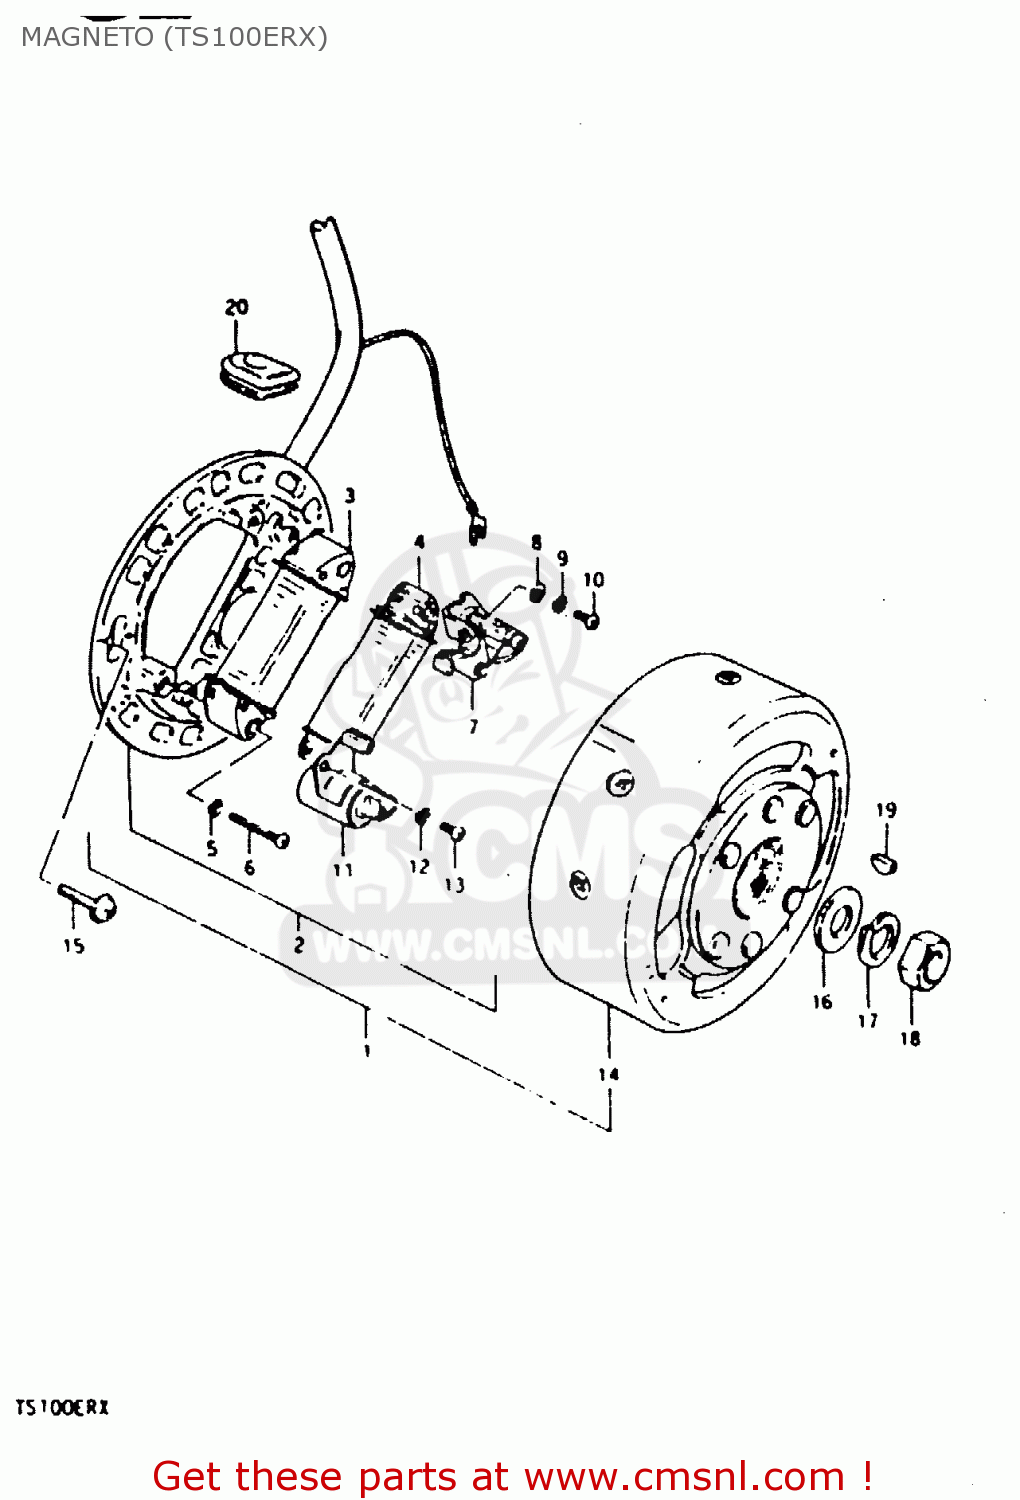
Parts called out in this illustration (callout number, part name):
1	MAGNETO ASSY
2	STARTER ASSY
3	COIL, LIGHTING
4	COIL,PRIMARY
5	LOCK WASHER
6	SCREW (4X30)
7	POINT ASSY,CONTACT
8	WASHER
9	LOCK WASHER
10	SCREW(4X10)
11	CONDENSER
12	LOCK WASHER
13	SCREW
14	ROTOR
15	SCREW(5X14)
16	WASHER
17	LOCK WASHER
18	NUT (10MM)
19	KEY
20	GROMMET
